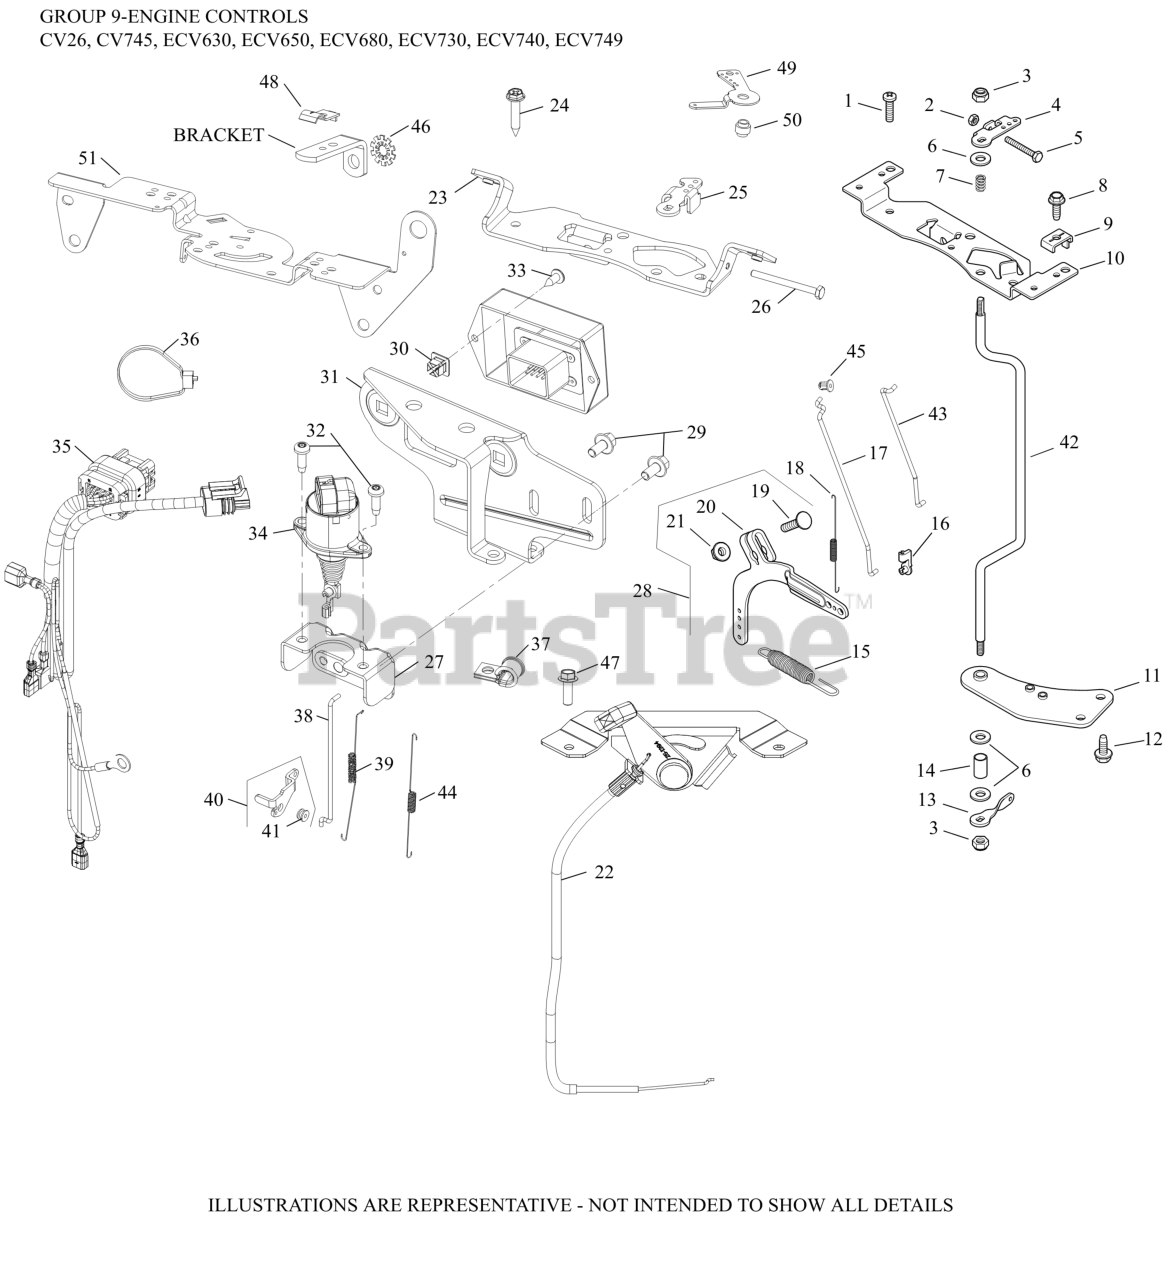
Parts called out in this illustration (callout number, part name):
2	NUT, M4X0.7
3	NUT, LOCK M6X1.0
4	LEVER, THROTTLE CONTROL
5	SCREW, CAP M4X.7X30
6	WASHER, FLAT 1/4"
7	SPRING, THROTTLE SHAFT
8	SCREW, THREAD FORMING
8	SCREW, MATHREAD M5 X 0.8 X 16
9	CLAMP, CABLE-(#2523753S)
10	BRACKET, CONTROL
11	BRACKET, THROTTLE SHAFT
12	SCREW, THREAD FORMING
13	LEVER, THROTTLE CONTROL
15	SPRING, GOVERNOR (ORANGE)
16	BUSHING, THROTTLE LINKAGE
17	LINKAGE, THROTTLE
18	SPRING, LINKAGE
19	BOLT, RD HD SQ NECK M6X1.0X25
20	LEVER, GOVERNOR - (#2409069S)
21	NUT, FLG M6X1.0
28	LEVER, GOVERNOR ASSEMBLY
42	THROTTLE CONTROL SHAFT
